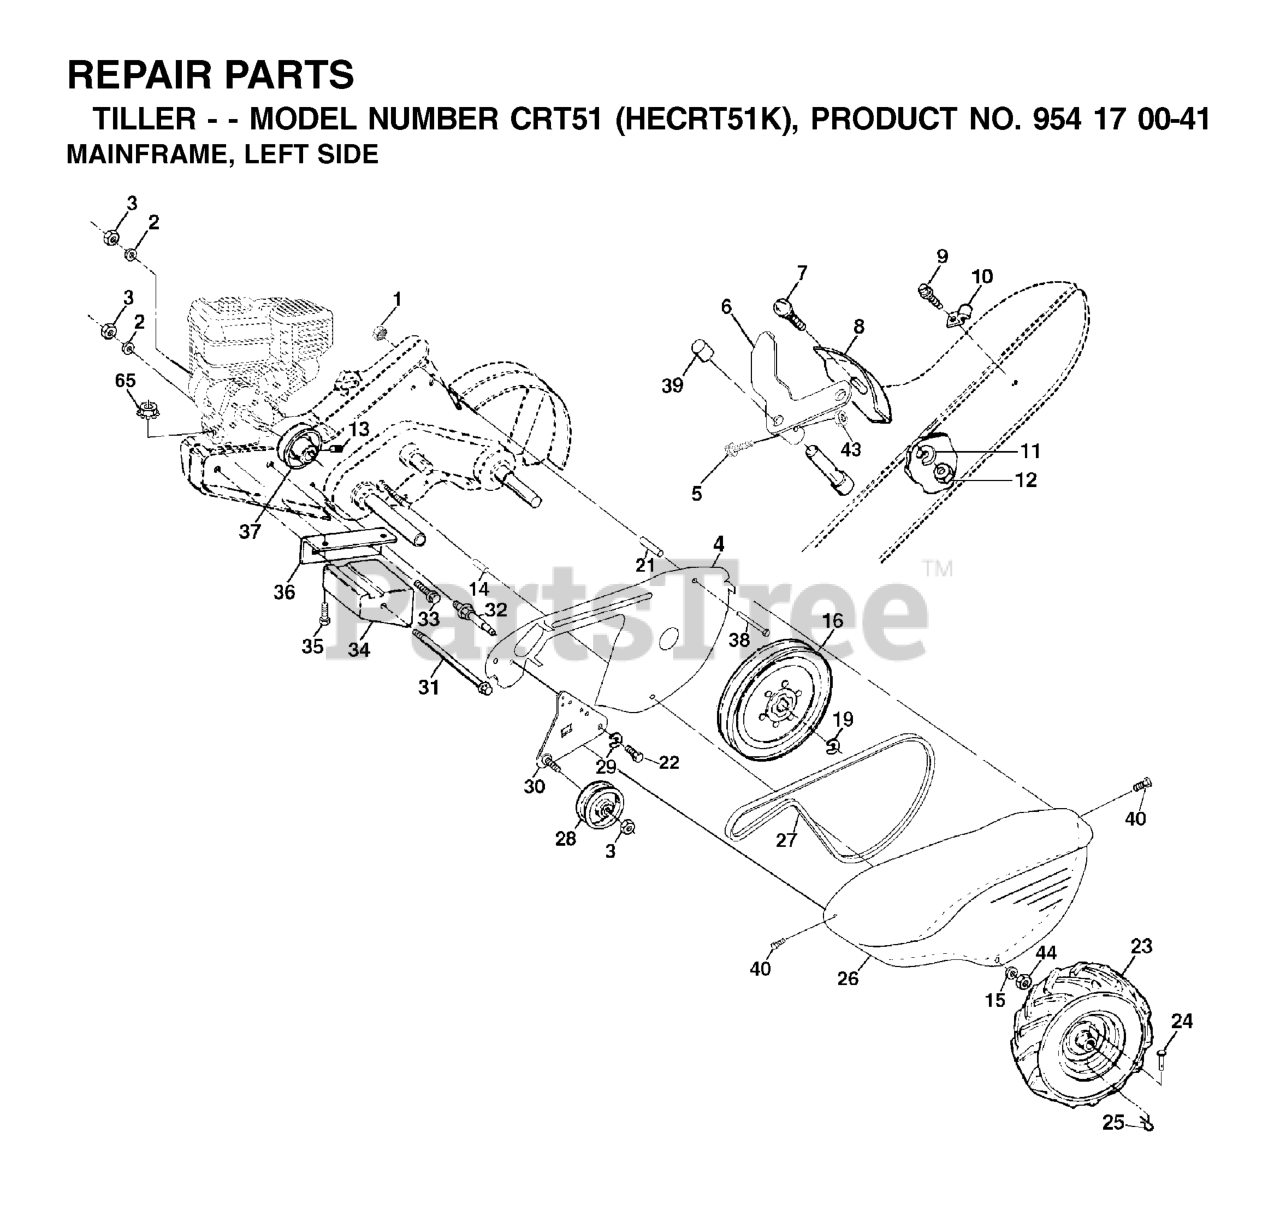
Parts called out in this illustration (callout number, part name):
1	NUT
2	WASHER, LOCK 3/8
3	NUT.HEX.3/8-16UNC
4	SHIELD
5	SCREW, SHIFT LEVER
6	LEVER ASM CRT
8	PANEL.INDICATOR.SHIFT.BLACK
9	TAPPING SCREW
10	CONDUIT.CLIP.PLATED
11	LOCKWASHER
12	NUT
14	SPACER-SPLIT.327 X .42
15	WASHER
16	SHEAVE, TRANSMISSION
19	RETAINING RING LT
21	SPACER CRT
23	TIRE.16X4-8.CHEVRON.TILLER
24	RIVET,DRILLED
25	RETAINER M
26	RP BELT GUARD
27	V-BELT
28	PULLEY-IDLER TI
30	BRACKET.ASM.IDLER.BLACK
31	BOLT.FIN.HEX.3/8-16UNC
32	SHIFT ARM CRT
33	BOLT
34	COUNTERWEIGHT.LH.CRT
35	Bolt Fin Hex 5/16 - 18 Unc x 2 Gr. 2
36	BRACKET LH CRT
37	RP.ENGINE PULLEY
38	BOLT
39	CAP.PLUNGER.BLACK
40	SCREW.HEX.WSH.SLT.#10-24X.50
44	NUT.71038.31-18.HEX.NYLOCK
65	LOCKNUT-FLANGE 5/16-18
